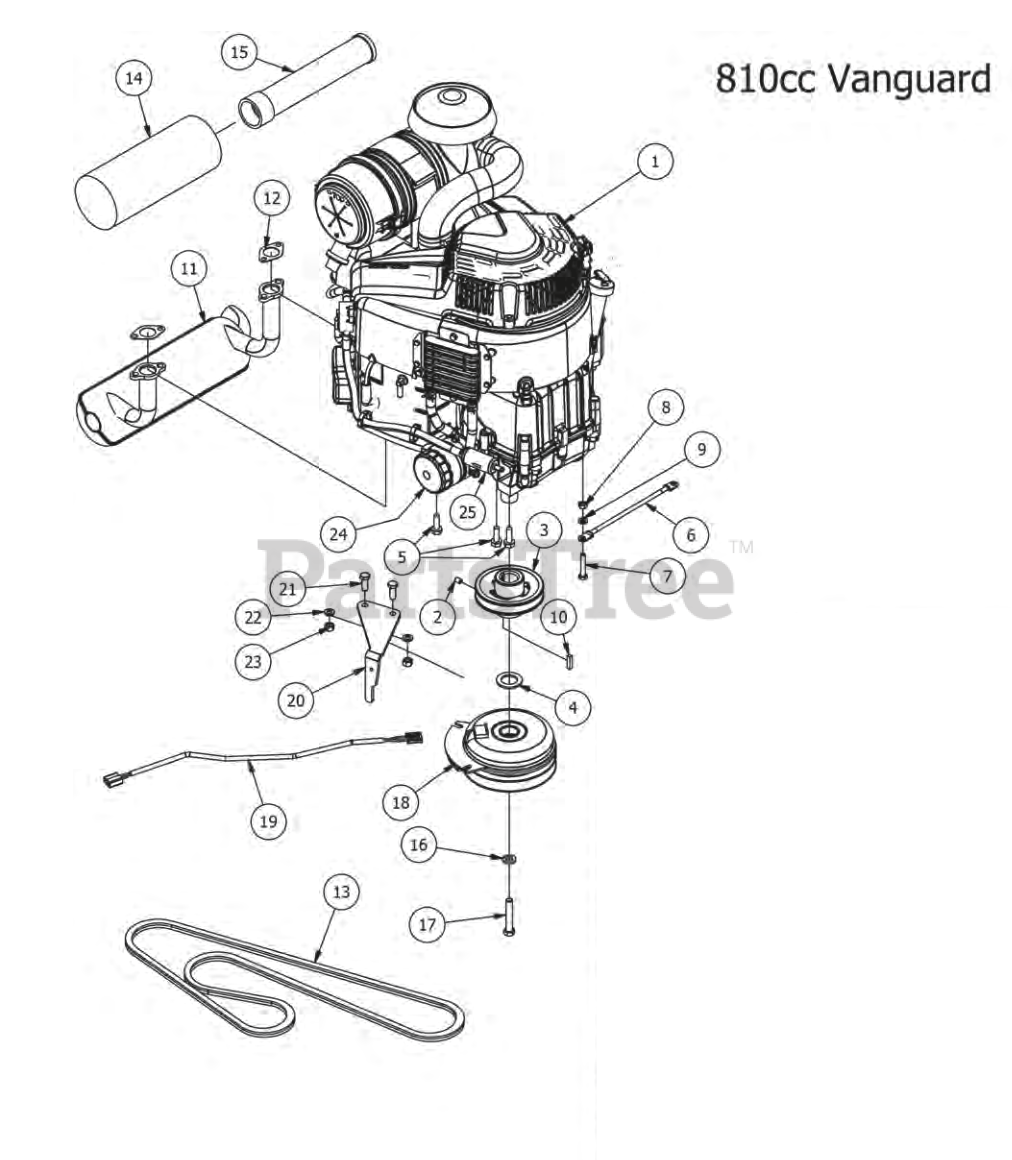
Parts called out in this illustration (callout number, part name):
1	810 Vanguard
2	3/8" Set Screw
3	4 3/4 Motor Pulley
4	1 1/8" Flat Spacer
5	3/8 x 1 1/8 bolt
6	Starter to chassis cable
7	5/16" x 1 3/4" Hex Bolt
9	5/16" Lock Washer
10	1/4" x 1" Key
11	Exhaust Briggs Engine
12	Exhaust gasket
14	Canister Air Filter-Outer
15	Canister Air Filter- Inner
16	7/16" Lock Washer
17	7/16" x 2 1/2" Hex Bolt
18	Clutch Assembly
19	Clutch Pigtail
20	PTO Engager Holder
21	3/8" x 1" Hex Bolt
22	3/8" Lock Washer
23	3/8" Hex Nut
24	Briggs Oil Filter
25	Universal Inline Fuel Filter
